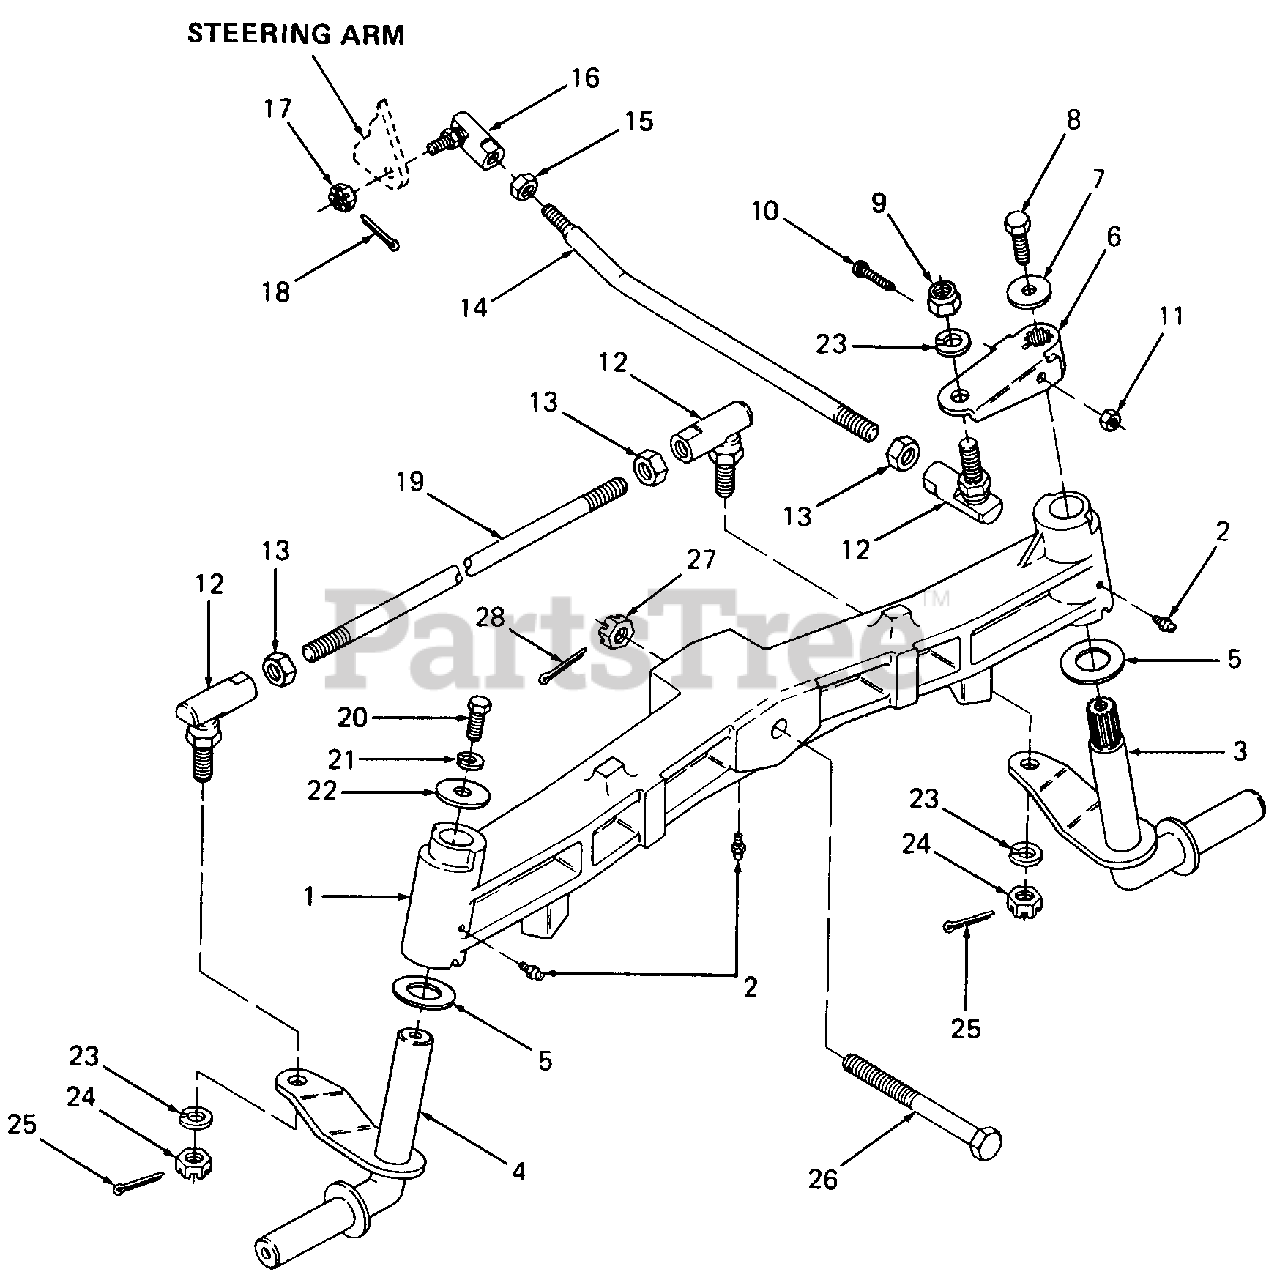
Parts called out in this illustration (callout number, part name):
3	Knuckle, Steering - LH
4	Knuckle, Steering - RH
5	Washer, Thrust, 1.03 X 1.62 X .03 Thk HDN
6	Arm, Steering
7	Washer, Flat, .406 X 1.25 X .157 Thk
8	Bolt, Hex Patch, 3/8-16 X 1.0 Lg GR5
9	Nut, Hex Top Lock, 1/2-20
10	Screw, Socket Hd Cap, 1/4-20 X 1.38 Lg
11	Nut, Hex Patch Lock, 1/4-20
12	Ball Joint
13	Nut, Hex Jam, 1/2-20 GR5
14	Link, Drag
15	Nut, Hex Jam, 3/8-24 GR5
16	Ball Joint
17	Nut, Hex Castle, 3/8-24 GR5
18	Pin, Cotter, 3/32 Dia X .75 Lg
20	Screw, Hex Cap, 3/8-16 X 1.0 Lg GR5
21	Washer, Lock, 3/8
22	Washer, Flat, .406 X 1.5 X .12 Thk
23	Washer, Lock, 1/2
24	Nut, Hex Castle, 1/2-20 GR5
25	Pin, Cotter, 3/32 Dia X 1.25 Lg
26	Bolt, Hex, 3/4-10 X 5.25 Lg GR5
27	Nut, Hex Castle, 3/4-10
28	Pin, Cotter, 1/8 Dia X 1.5 Lg
